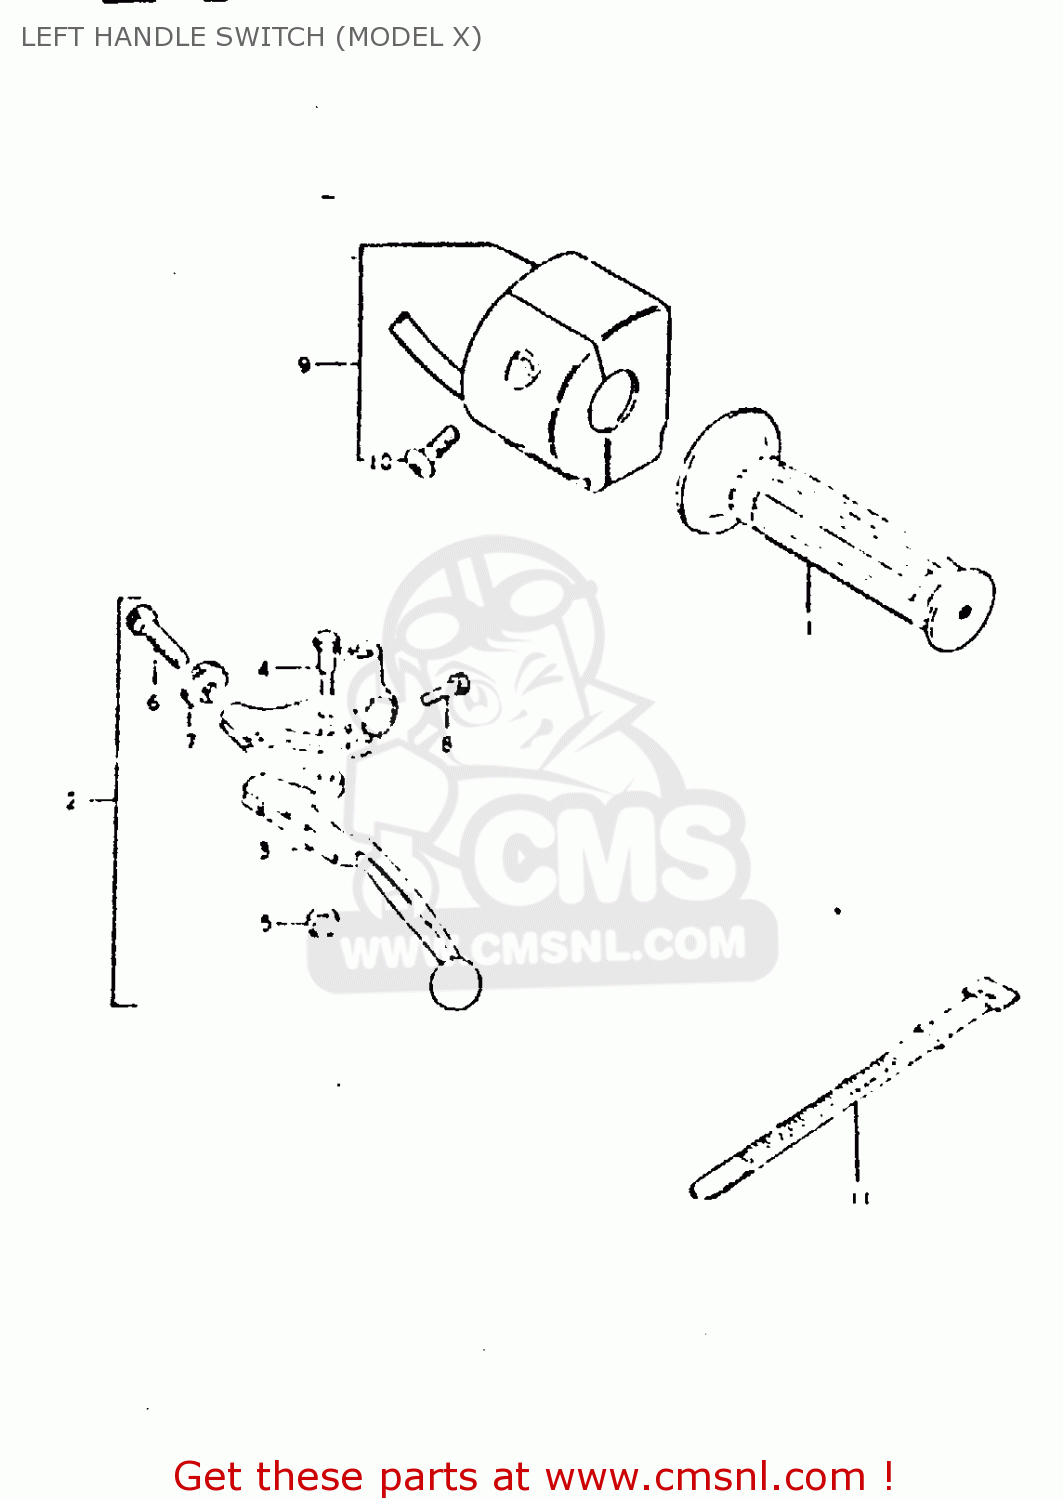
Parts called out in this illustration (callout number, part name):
1	GRIP,LEFT
2	LEVER ASSY, CLUTCH
3	LEVER,CLUTCH
4	BOLT,LEVER
5	NUT 6MM
6	ADJUSTER,CABLE
7	NUT,CABLE ADJUSTER
8	BOLT
9	SWITCH ASSY, HANDLE LH
10	SCREW
11	CLAMP(L:120)
